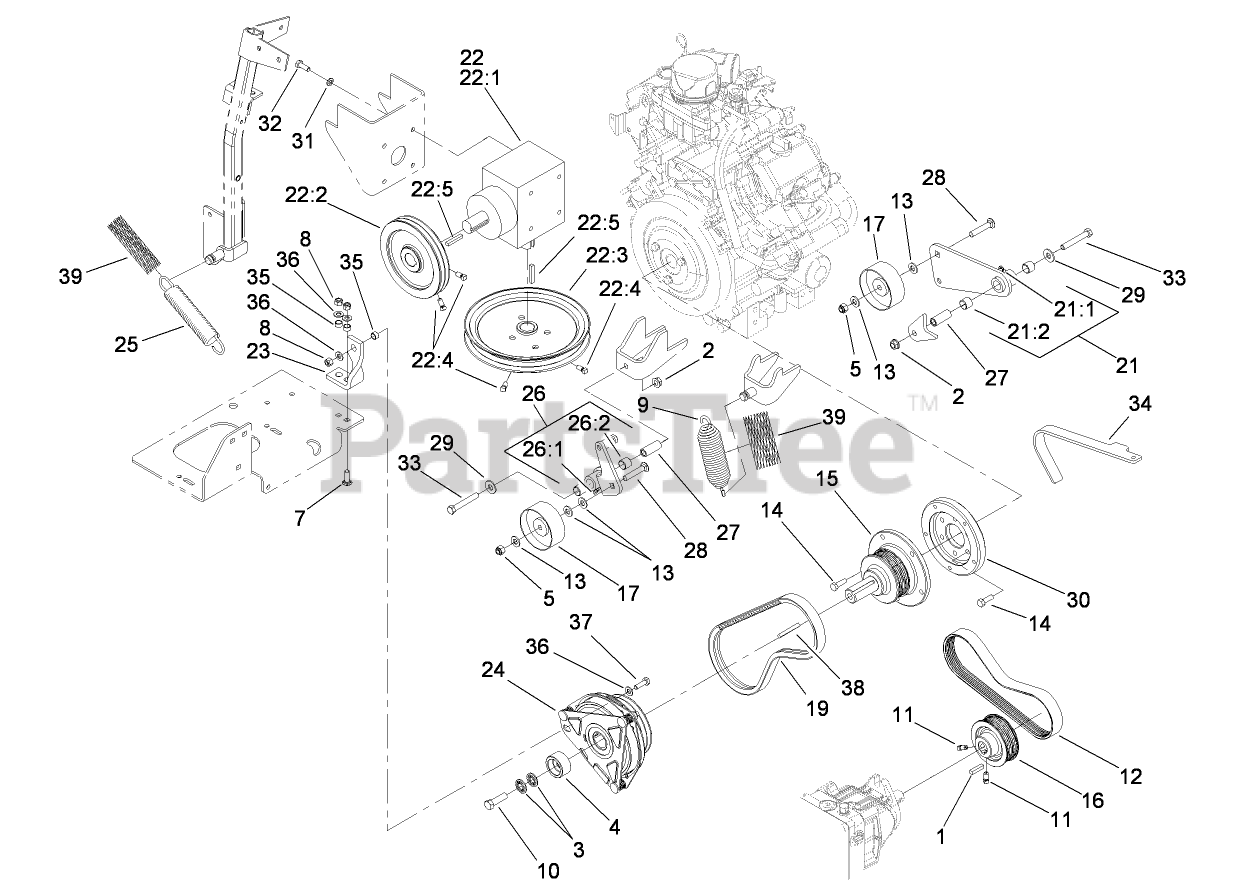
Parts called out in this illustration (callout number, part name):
2	NUT-HHF, WHIZ
3	WASHER-SPRING
4	RETAINER-CLUTCH
5	NUT-LOCK, NI
7	SCREW-CARR
8	NUT-LOCK, NI
9	SPRING-EXTENSION
10	SCREW-HH
11	SCREW-SET
12	BELT-V
13	WASHER-FLAT
14	SCREW-HH
15	SHAFT-STUB
16	PULLEY
17	PULLEY-FLAT
19	BELT-V
21	IDLER ARM ASM
21:1	FITTING-GREASE
21:2	SLEEVE-BEARING
22	Gearbox ASM
22:1	GEARBOX-90 DEG
22:2	PULLEY
22:3	PULLEY
22:4	SCREW-SET
22:5	KEY-SQUARE
23	STRAP-STOP, CLUTCH
24	CLUTCH-ELECTRIC
25	SPRING-IDLER, DECK
26	IDLER ARM ASM
26:1	FITTING-GREASE
26:2	SLEEVE-BEARING
27	BUSHING
28	SCREW-CARR
29	WASHER-FLAT
30	ADAPTER-SHAFT, STUB
31	WASHER-LOCK
32	SCREW-HH
33	SCREW-HH
34	TOOL-ALIGNMENT, PULLEY
35	SPACER
36	WASHER-PLAIN
37	SCREW-HH
38	KEY-SQUARE
39	COVER-SPRING
